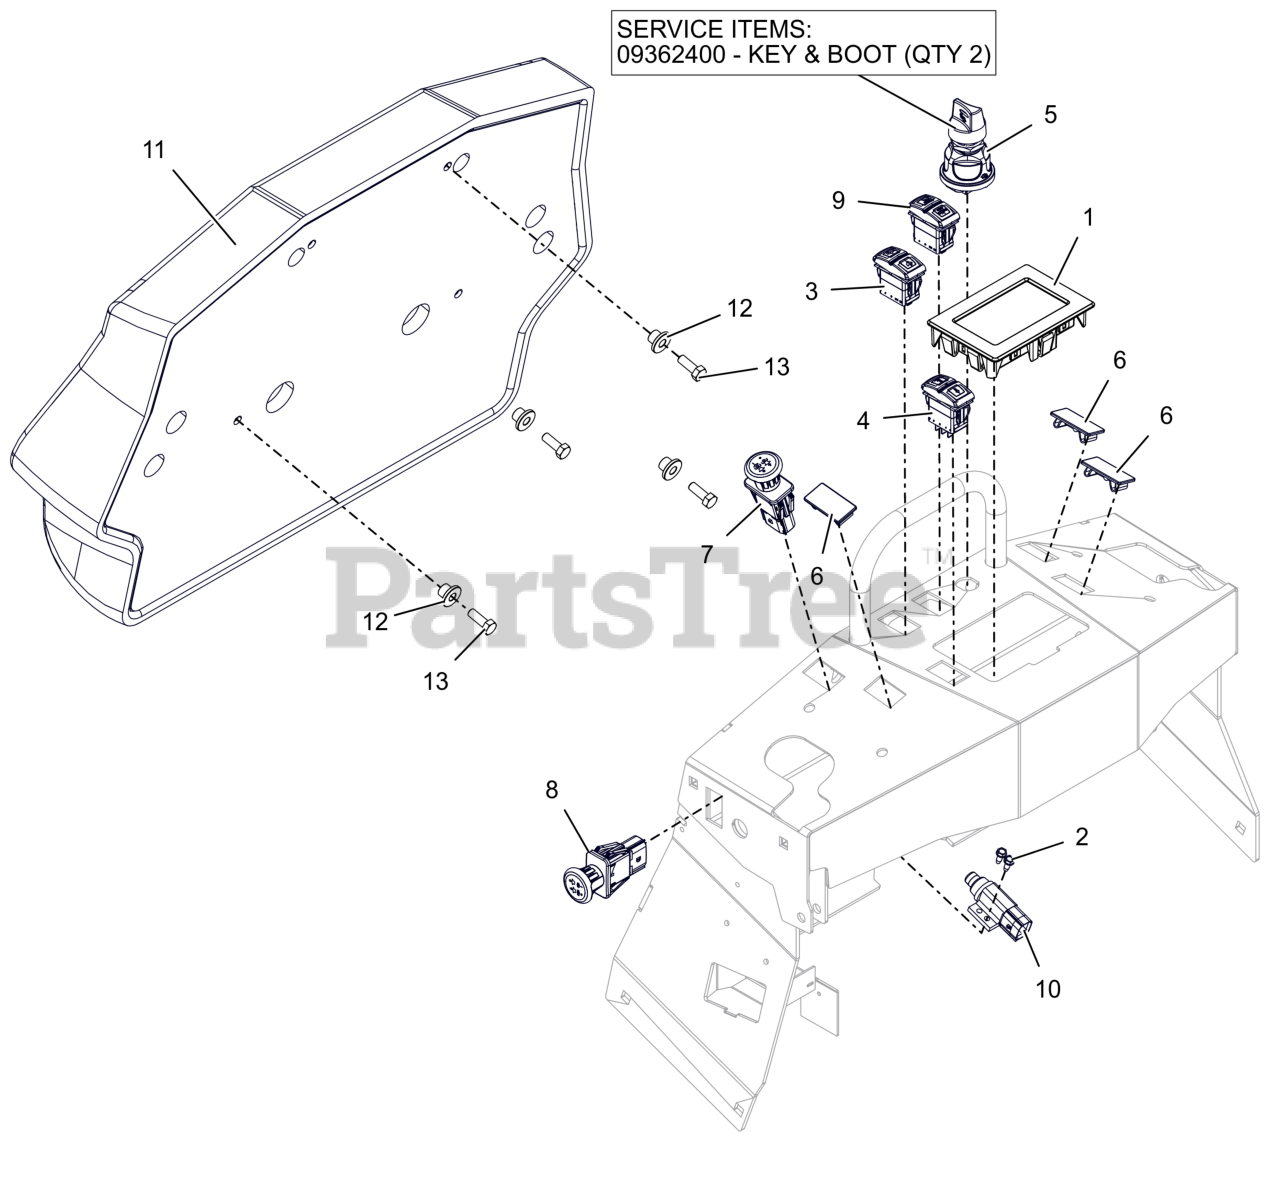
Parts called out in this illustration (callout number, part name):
1	DISPLAY, PSEV
2	SCR,TAP #10-24X.50 HWH TR ZCC
3	SWITCH, TOGGLE - SPEED
4	SWITCH, ROCKER - DISPLAY
5	SWITCH, KEY (SEALED)
5	KEY & BOOT (Qty 2)
6	PLUG, SWITCH
7	SWITCH, PTO - RED
8	SWITCH, PARKING BRAKE
9	SWITCH, TOGGLE ECO
10	SWITCH, SEALED PLUNGER
11	PAD, ARIENS ARROW OPERATOR
12	BSHG-FLG .325X.500X.513X.875
13	BLT, HEX .31-18X.875 G5 ZCC
